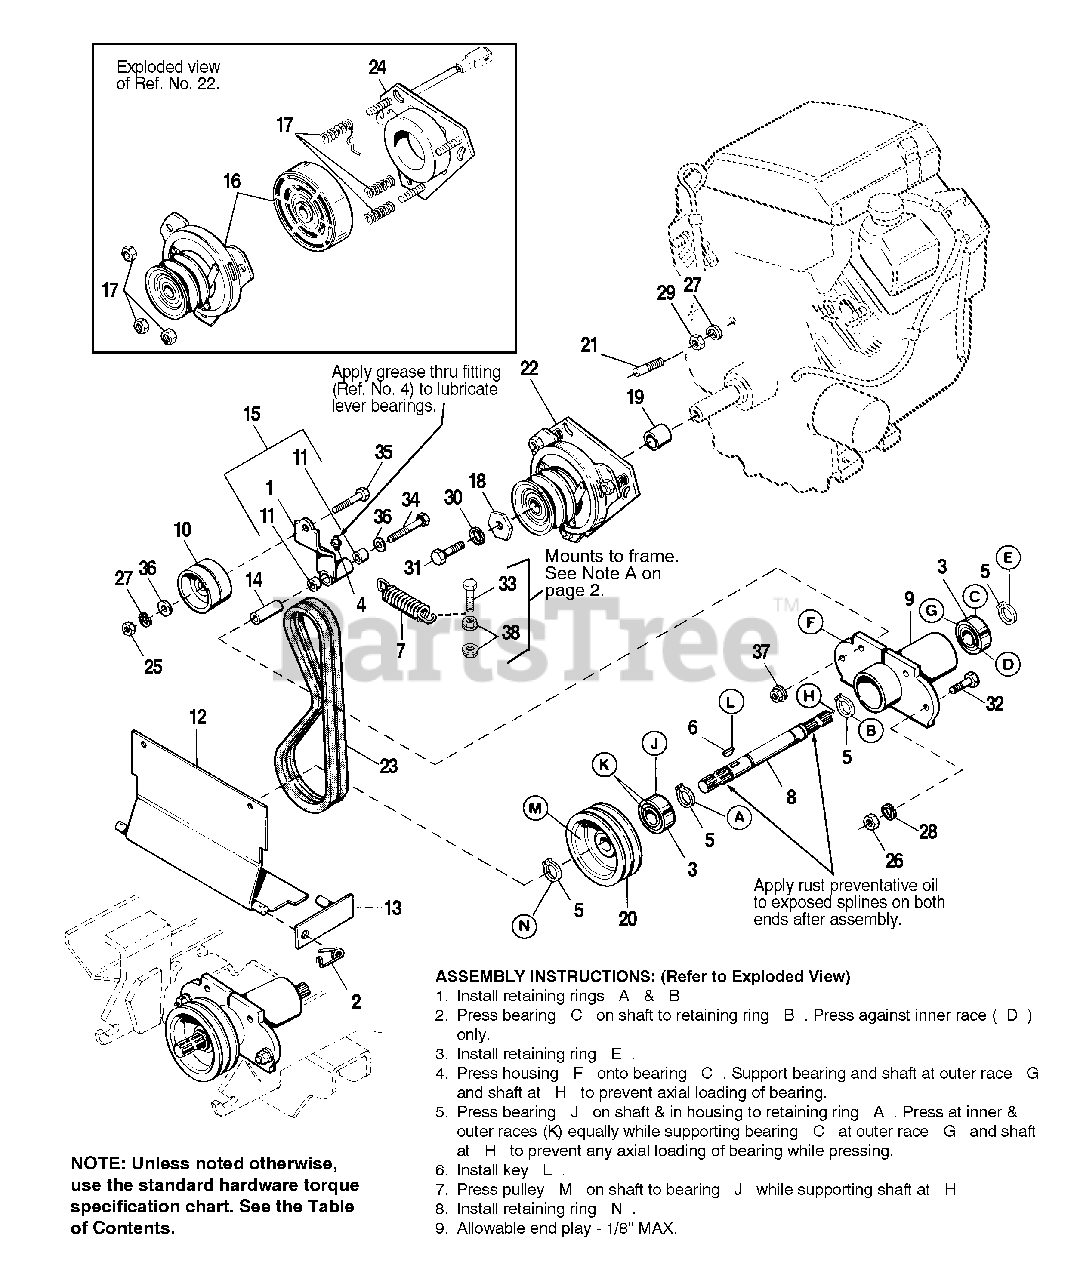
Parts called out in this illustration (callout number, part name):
2	RETAINER, Pin Spring
3	BEARING, Ball, 1-3/16 x 2-7/16 x 5/8
4	FITTING, Grease
5	RING
6	KEY, Hi-Pro, 1/4 x 3/4
7	SPRING, Tension (Later Models-refer to illustration)
8	SHAFT, Spline, PTO
9	HOUSING & PLATE ASSY.
10	PULLEY, Idler, 3-1/4 Dia.
11	BUSHING, Idler Arm
12	GUARD ASSY.
13	LINK & PIN ASSY., Guard
15	IDLER ARM ASSY. (Incl. Ref. Nos. 24 & 25)
16	ROTOR ASSEMBLY & ARMATURE ASSEMBLY KIT
17	ACCESSORY KIT (Nut & Springs)
18	WASHER, Hex
20	PULLEY, PTO Drive
21	STUD, Clutch, Torque
22	ROTOR ASSY. & ARMATURE ASSY. KIT
23	BELT SET, PTO Drive (Matched Set of 2)
24	CLUTCH, Electric (Incl. Ref. Nos. 36, 37 & 38 )
25	NUT, Hex, Full, 3/8-16
26	NUT, Hex 1/2-13 (1691847) NUT, Hex 1/2-13 (1691848, 1691849) NUT, Hex 1/2-13 (1691850)
27	LOCKWASHER, Spring, 5/16
28	LOCKWASHER, Spring 1/2 (1691847) LOCKWASHER, Spring 1/2 (1691848, 1691849) LOCKWASHER, Spring 1/2 (1691850)
29	NUT, Hex Jam, 3/8-16 NC-2B
30	LOCKWASHER, Spring, 7/16
31	SCREW, Hex Hd., 7/16-20 x 2.0, Gr. 5
32	CAPSCREW, Hex, 1/2-13 x 1-1/4 (46" &66" Mowers only)
33	BOLT, 3/8-16 X 1-3/4, GR 5, CZ
34	CAPSCREW, Hex Head, 3/8-16 x 2-1/2, Black
35	CAPSCREW, Hex Head, 3/8-16 x 2, GR5
36	WASHER, 3/8, .41 ID x .87 OD x .08 THK
37	NUT, Hex Flange, Two Way Lock, 3/8-16
38	NUT, Hex Flange Whiz Lock Small, 3/8-16
